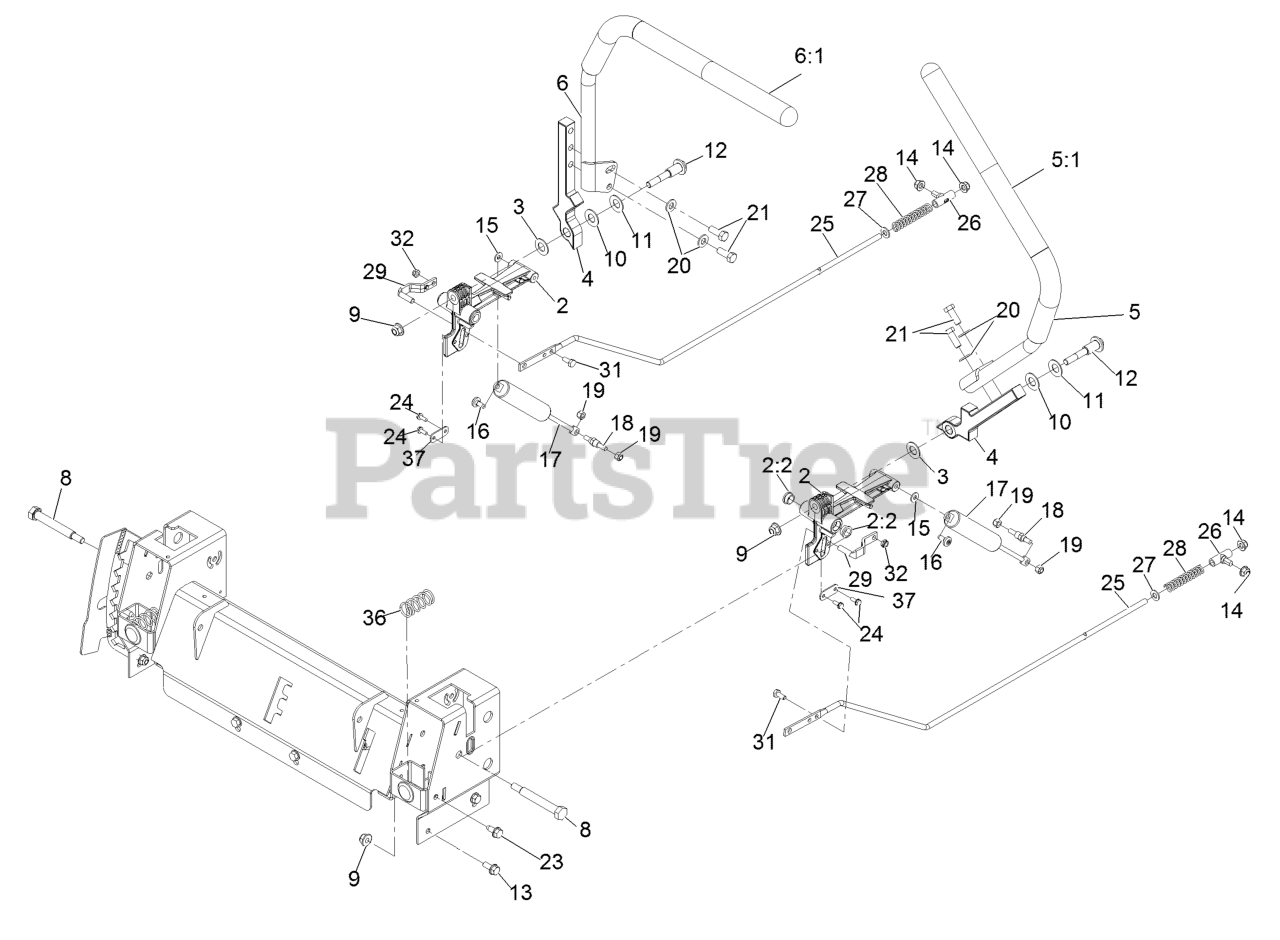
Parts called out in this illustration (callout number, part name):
2	Actuator Arm ASM
2:2	Bushing-Flange
3	Washer-Nylon
4	Arm-Control
5	Handle-Control, LH
6	Handle-Control, RH
8	Bolt-Pivot
9	Nut-Nyloc 3/8-16 Flg
11	Washer-Belleville
12	Bolt-Pivot
13	Screw-HH Flg 5/16-18 X 3/4
14	Nut-Nyloc 5/16-18 Flg
16	Screw-1/4-20 X 1/2 Tf Torx Plus
18	Stud-Damper
19	Nut-Nyloc 1/4-20
20	Washer-3/8 SAE
21	Screw-HH 3/8-16 X 1
23	Screw-HWH 5/16-18 X 3/4 Tf
24	Screw-HWH #10-24 X 1/2 Taptite
25	Rod-Hydro
26	Mount-Rod, Hydro
27	Washer-5/16 SAE
29	Pin-Rod, Hydro
31	Screw-HH 1/4-20 X 5/8
32	Nut-Nyloc 1/4-20 Thin
36	Spring-Return
37	Plate-Stop, Hydro
